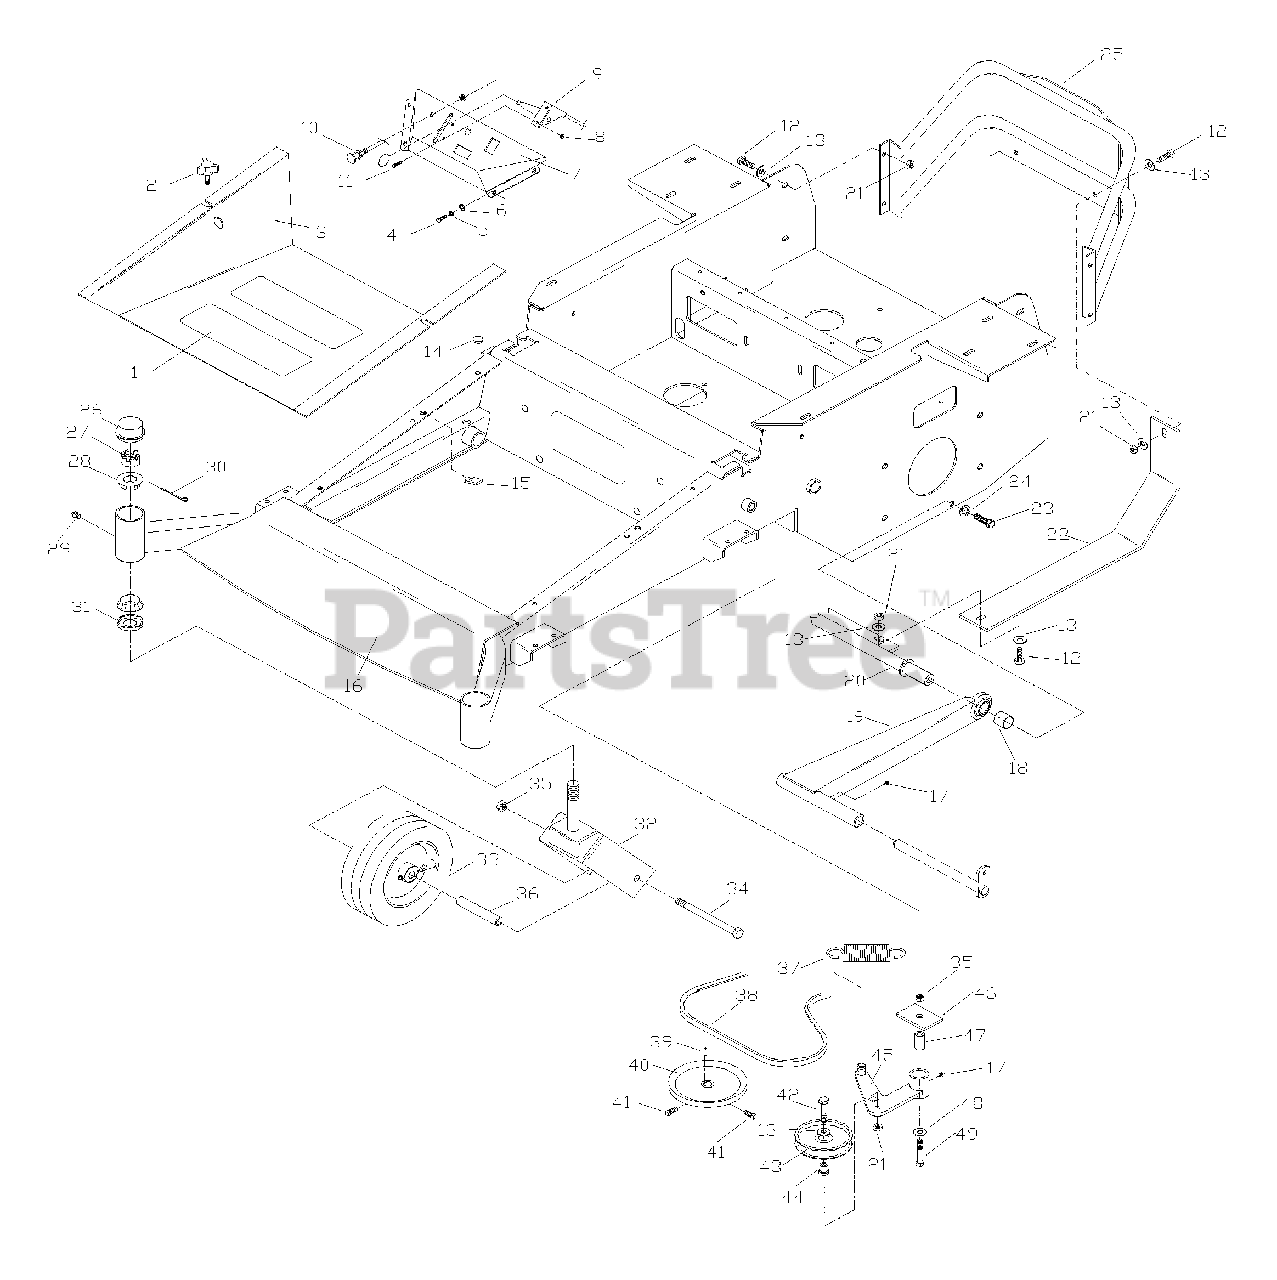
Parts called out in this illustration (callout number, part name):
1	ANTI-SKID PAD
2	KNOB W/ STUD
3	FOOT PLATE
4	HCS 1/4C X 3/4"
5	1/4" LOCK WASHER
6	1/4" FLAT WASHER
7	CONSOLE W/ DECAL
8	# 10-24 NYLOC NUT
9	THROTTLE CABLE
10	CHOKE CABLE
11	#10-24 X 1/2" HCS
12	HCS 3/8C X 1"
13	... 3/8 FLAT WASHER
16	MAIN FRAME W/DECALS
17	ZERK
18	STRUT SPACER
20	CROSS SHAFT
21	3/8C CENTERLOCK
22	SKID PLATE
23	HCS 7/16C X 1"
24	7/16 LOCK WASHER
25	REAR GUARD
26	CAP, GREASE
27	CASTLE NUT 1" C
28	BEARING W/CUP
29	DRIVE IN ZERK
30	COTTER PIN 1/8 X 2"
32	YOKE, CASTER
33	TIRE & WHEEL ASM.
33	RIM
33	TIRE
33	FLANGE BEARING
33	2.5" ROLLER BEARING
34	HCS 1/2-13 X 7.5" GD. 5
35	1/2C NYLOC NUT
36	SPACER, CASTER
38	PUMP BELT
39	5MM X 25MM KEY SQ.
41	5/16C X 5/8 SET SCREW
42	HCS 3/8C X 1.75
43	IDLER PULLEY
44	IDLER FLANGE BUSHING
45	IDLER ARM
46	SUPPORT PLATE
47	PIVOT BUSHING
48	1/2 FLAT WASHER
49	HCS 1/2C X 3.25 GD. 5
